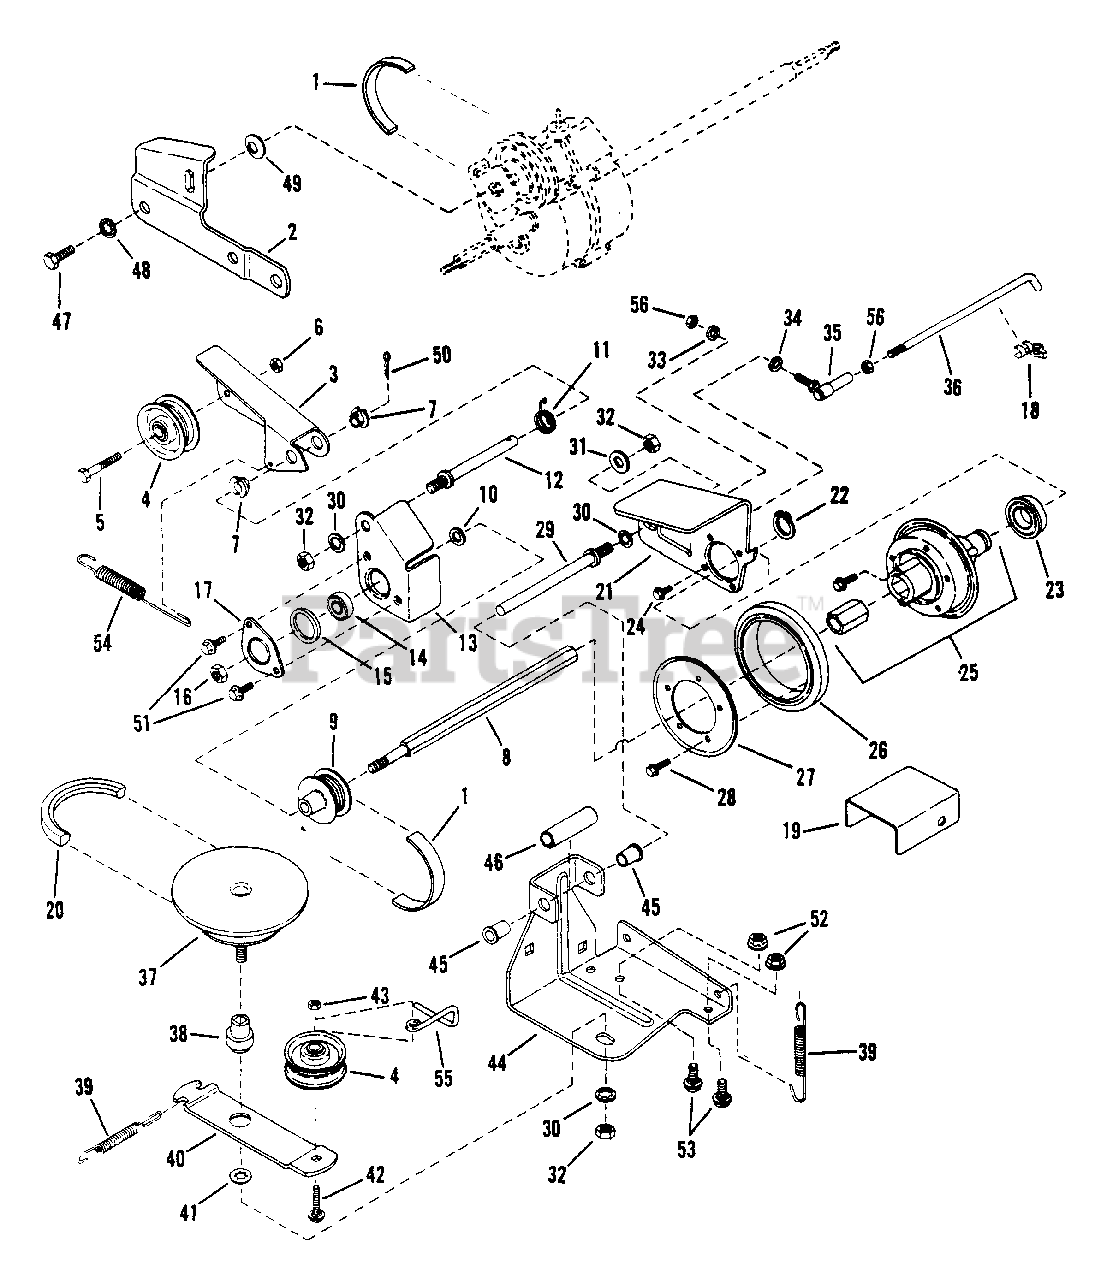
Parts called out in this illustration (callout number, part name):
1	BELT, Poly-Vee
2	LINK, Differential
3	ARM, Clutch Idler
4	PULLEY, Idler
5	SCREW, 1/4-28 x 1-3/8" Hex Head Cap
6	NUT, 1/4-28 Hex Lock
7	BUSHING, 3/8 I.D. Nylon
8	SHAFT, Hex
9	PULLEY, Poly-V
10	WASHER, 3/8" Flat
11	SPRING, Torsion
12	STUD
13	HOLDER, Bearing (Inner Half)
14	BEARING, Ball
15	O-RING
16	NUT, 3/8-24 Hex Center Lock
17	HOLDER, Bearing (Outer Half)
18	CLIP, 1/4 Right Arc (Transfer Rod)
19	SHIELD, Hex Shaft
20	BELT, Engine Drive
21	PLATE, Thrust
22	RING, Retaining
23	BEARING, Ball
24	SCREW, #10-32 x 1/4" Self-Tapping Machine
25	ASSEMBLY, Hub
26	RING, Driven
27	PLATE, Ring Retaining
28	SCREW, #10-24 x 1/2" Hex Washer Self-Tap (Torx)
29	GUIDE, Thrust Plate
30	WASHER, 3/8 Internal Tooth Lock
31	WASHER, 3/8" Flat
32	NUT, 3/8-24 Hex
33	WASHER, 1/4 Flat
34	WASHER, 1/4 Internal Tooth Lock
35	JOINT, Ball
36	LINK, Transfer
37	ASSEMBLY, Drive Disc
38	BUSHING
39	SPRING (Wheel Drive & Idler)
40	ARM, Idler
41	RETAINER, 3/8 Bolt
42	BOLT, 1/4-20 x 1-1/2" Carriage
43	NUT, 1/4-20 Hex Center Lock
44	BRACKET, Deck
45	BUSHING, Flange
46	SPACER
47	SCREW, 5/16-18 x 1/2" Hex Head Cap
48	WASHER, 5/16 Internal Tooth Lock
49	WASHER, Spring
50	PIN, 3/32 x 1/2" Cotter
51	SCREW, 1/4-20 x 1/2" Self-Tapping
52	NUT, 5/16-18 Hex Flange Lock GR 5
53	BOLT, 5/16-18 x 5/8" Short Neck Carriage
54	SPRING, Clutch
55	SCRAPER, Drive Pulley
56	NUT, 1/4-28 Hex
